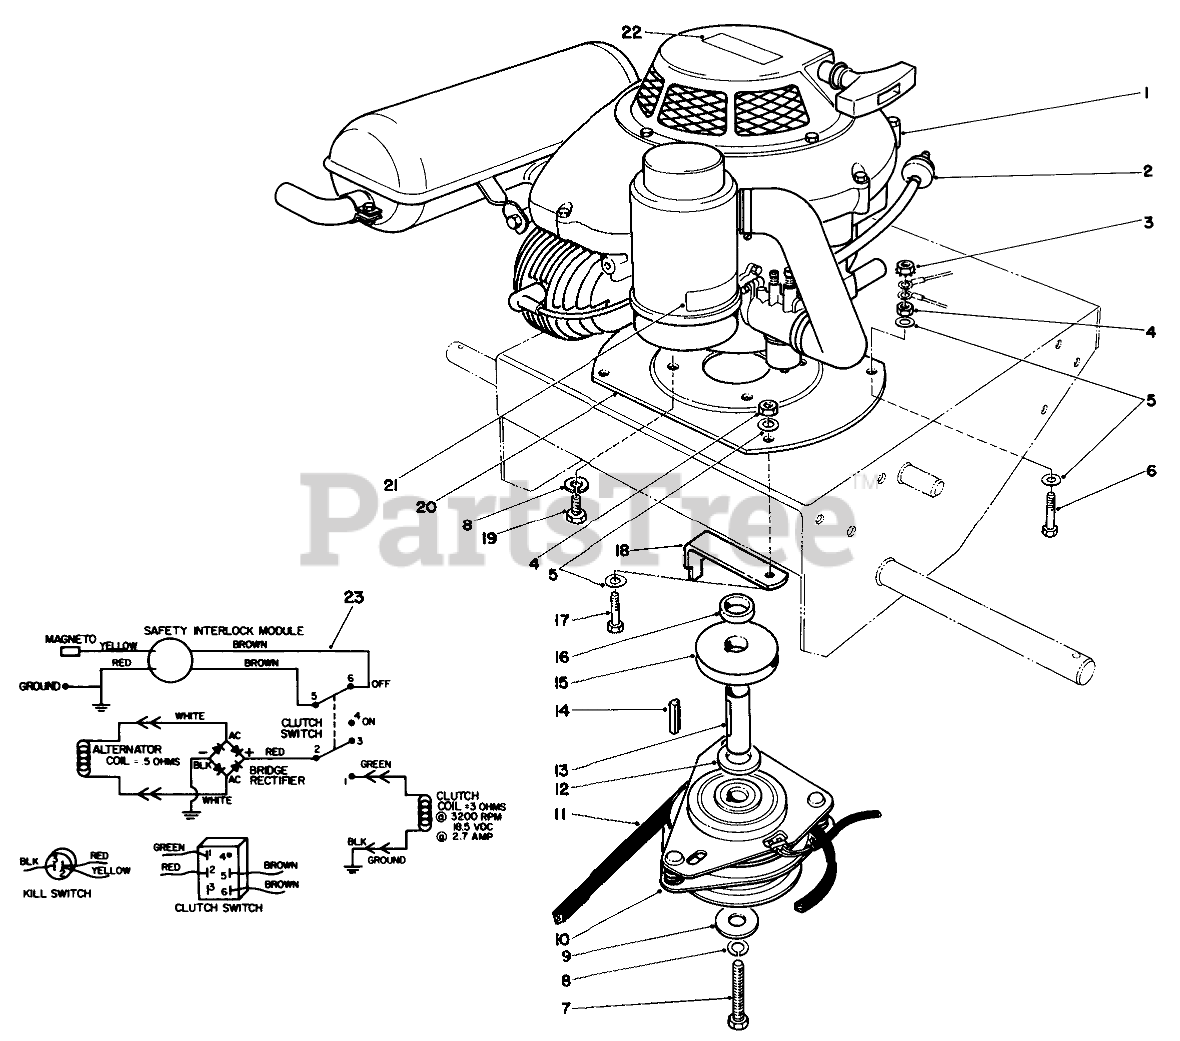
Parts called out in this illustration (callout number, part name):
1	Engine Assembly
2	Nut
3	NUT-KEPS
4	NUT-LOCK, CONE
5	WASHER-PLAIN
6	SCREW-HH
7	CAPSCREW
8	WASHER-LOCK
9	WASHER-CLUTCH
10	CLUTCH/BRAKE
11	V-BELT, DRIVE
12	SPACER-LOWER
13	Adapter-Crankshaft
14	CRANKSHAFT KEY
15	Pulley-Drive
16	UPPER SPACER
17	SCREW-HH
18	Retainer-Clutch
19	CAPSCREW
20	ENGINE PLATE
21	DECAL
22	DECAL
23	JLO WIRE HARNESS
